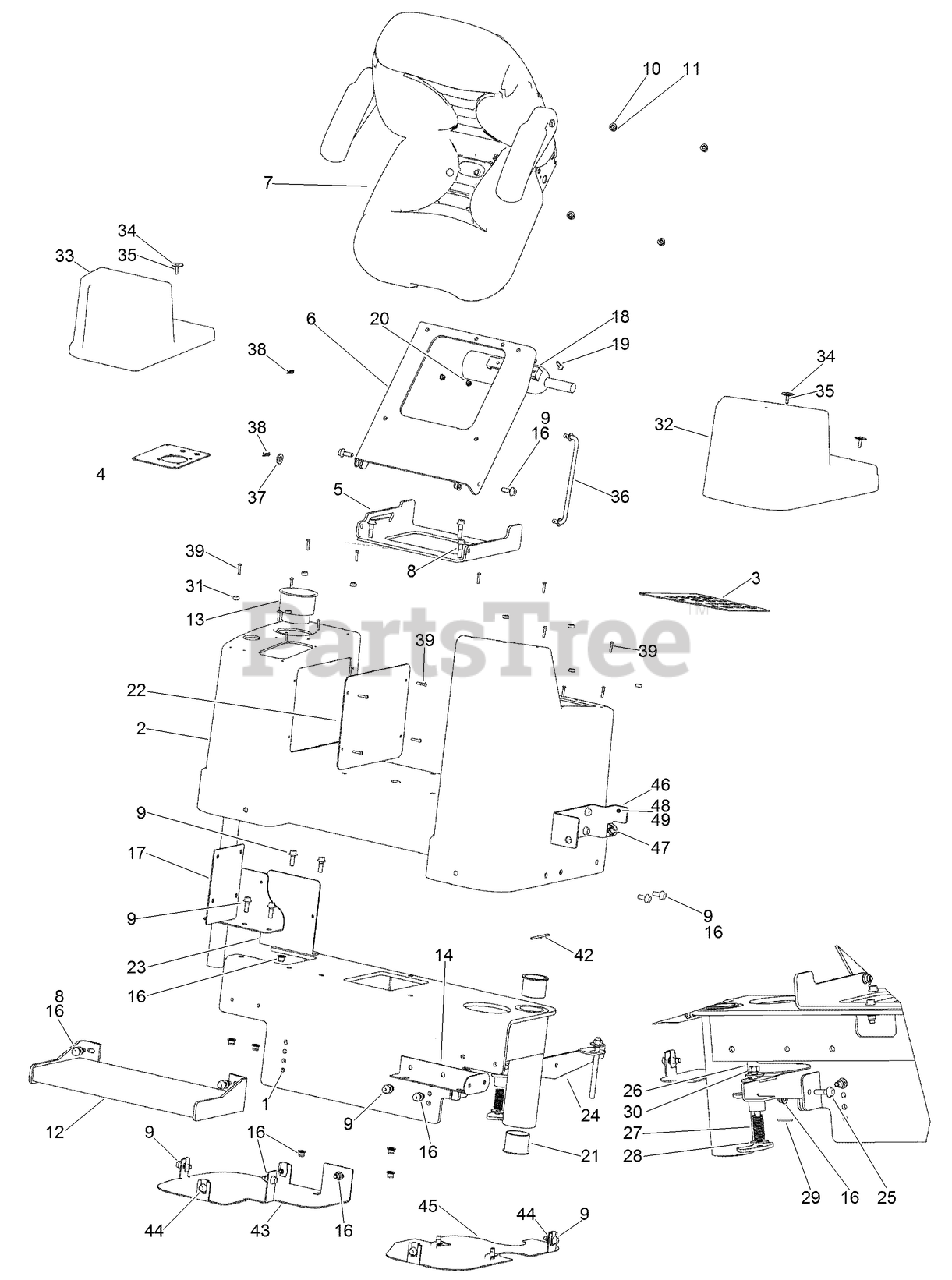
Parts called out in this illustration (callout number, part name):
1	WELDMENT - Operators Console
2	CONSOLE - Fiberglass
3	PLATE - Cover, Left Console
4	PLATE - Mounting
5	PLATE - Seat Mount Bottom
6	PLATE - Seat Mount Top
7	OPERATOR SEAT ASM (STATIC)
8	SCREW-HHF
9	SCREW-HH
10	WASHER - 0.406 x 0.750 x 0.119 in CST ZND
11	NUT - Hex .375 - 16 GR8 PHC
12	ASSEMBLY - Foot Rest
13	CUP-HOLDER
14	WELDMENT - Operators Console Support
16	NUT-FLANGE, NYLOCK
17	WELDMENT - Umbrella Mount
18	EXTINGUISHER - Fire
19	SCREW, METRIC FLANGE w/BODY-M6 x 25
20	NUT, METRIC FLANGE PREVAILING - M6 Zinc
21	BEARING-FLANGED
22	PLATE - Seat Ins Panel
23	PLATE - CPU Mount
24	ARM - Seat Adjustment
25	SCREW-HHF
26	ROD-SWING, SEAT
27	SPRING-PIVOT LOCK, SEAT
28	WASHER-FLAT
29	PIN-COTTER
30	NUT-Hex 0.500-13 GR5 ZND
31	GROMMET-RUBBER
32	COVER-PROTECTIVE, LEFT
33	COVER-PROTECTIVE, RIGHT
35	SCREW - Button Head (Allen)
36	ROD-PROP, SEAT
37	WASHER-FLAT
38	PIN - Cotter Hair Int 3/16 in ZND
39	SCREW - PHD Type 1, #10 - 24 x 1.00 CST ZND
42	PIN-COTTER
43	PLATE - Splash Guard
45	PLATE - Splash Guard
46	PLATE - Cord Retaining
47	CLIP - Tool
48	SCREW - PHd Type 1 #6 - 32 x 0.500 CST ZND
49	NUT - KEPS Ext T Wshr #6 - 32 UNC ZP
